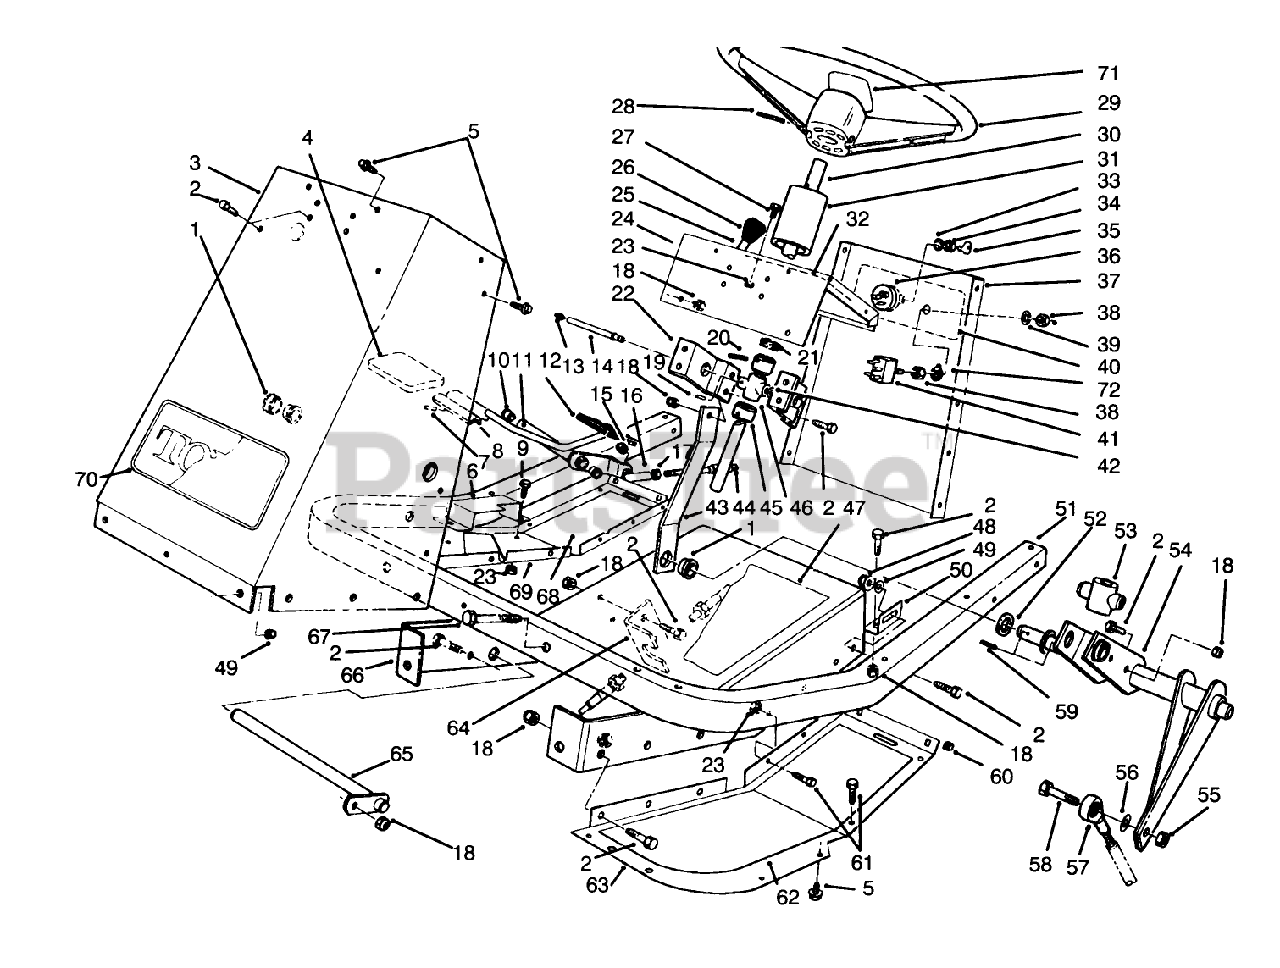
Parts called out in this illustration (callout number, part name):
1	BEARING-FLANGE
2	SCREW-HH
3	Tower-Front
4	FORWARD PEDAL PAD
5	SCREW-HHFTF
6	Footrest-Pedal
7	PIN-SPRING
8	ACCELERATOR PEDAL
9	SCREW-HH
10	BUSHING-FLANGE
11	Pedal-Traction (Incl. Ref. #10)
12	REVERSE PAD
13	FITTING-GREASE
14	TUBE ZERK
15	NUT-LOCK
16	JOINT-BALL
17	NUT-JAM
18	NUT-LOCK, NI
19	3/32 X 9/16 ROLL PIN
20	PIN-SPRING
21	COVER-DUST
22	BRG SUPT BRKT
23	NUT-LOCK, NI
24	Tower-Top
25	CONTROL-CHOKE,THROTTLE
27	SCREW-HH
28	PIN-ROLL
29	WHEEL-STEERING
30	STEERING SHAFT
31	STRG. SHAFT COVER
32	THROTTLE DECAL
33	Washer-Lock
35	KEY-IGNITION
36	Switch-Ignition (Incl. Ref. #33-35)
37	Panel-Tower Rear
38	NUT-HJ
39	WASHER-LOCK, INT
40	SWITCH DECAL
41	Switch-Clutch & Brake (Incl. Ref. # 38)
42	WASHER-BELLEVILLE
43	Link-Steering
44	TRACT CONT.CABLE
45	STRG SHAFT COLLAR
46	BRG STEERING SHAFT
47	TUNNEL DECAL
48	NUT-HF
49	WASHER-PLAIN
50	TUNNEL BRKT
51	Frame-Footrest
52	WASHER-THRUST
53	STEER.SHAFT FOLLOWER
54	Follower Lever
55	NUT-HEX
56	WASHER-FLAT
57	BALL JOINT LH
58	SCREW-HH
59	PIN-ROLL
60	NUT-RETAINED
61	SCREW-HH
62	FOOT REST PAD LH
63	Footrest-L.H.
64	TRACT CABLE BRKT
65	PEDAL.SHAFT WA
66	Tunnel
67	SCREW-HH
68	FOOT REST PAD RH
69	Footrest-R.H.
70	DECAL
71	STRG-WHL INSERT TORO
72	TAB-WASHER
73	NUT-HEX, SPECIAL
